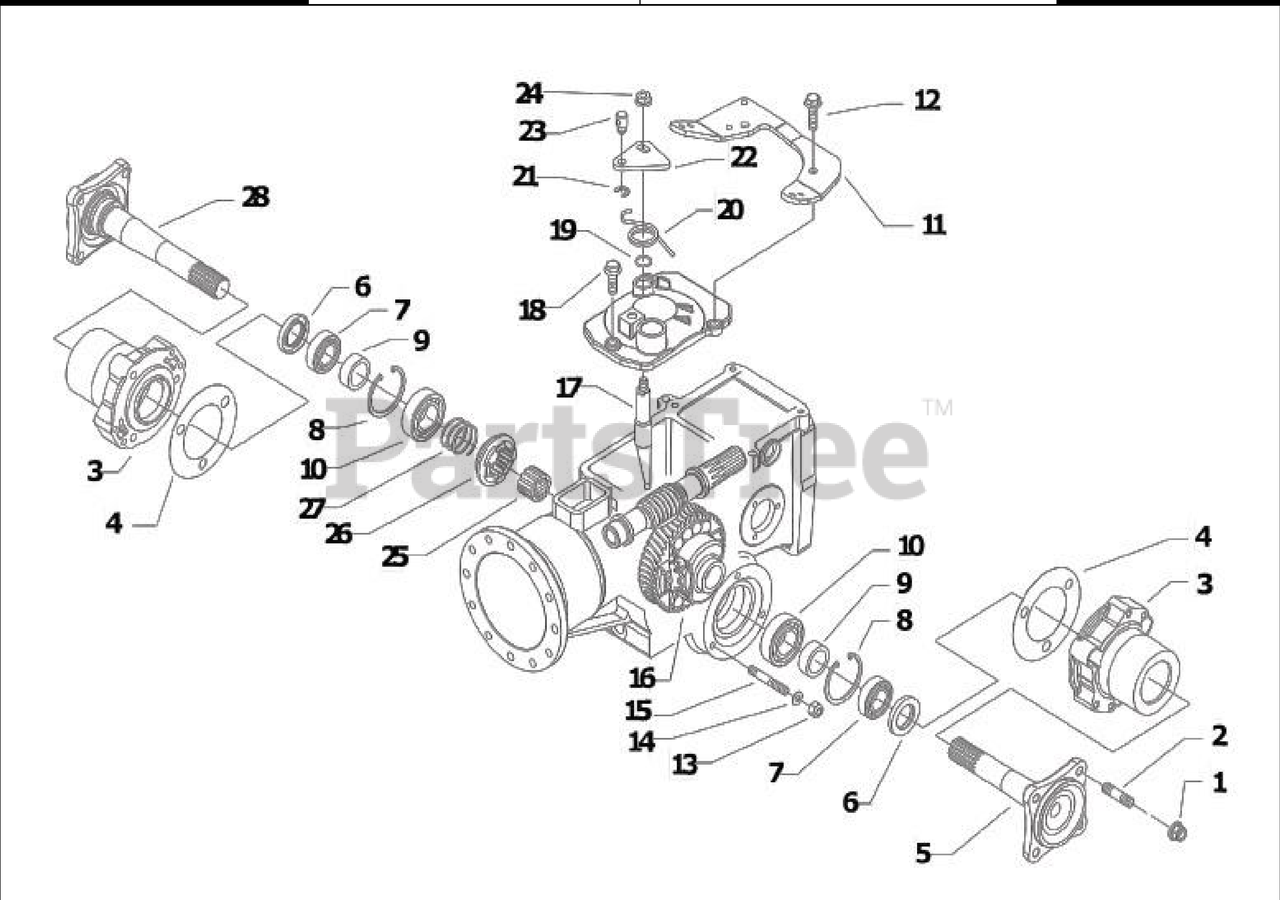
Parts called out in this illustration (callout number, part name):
1	SELFLOCK NUT M10
2	STUD BOLT M10X40X24X12
5	AXLE SHAFT (SHORT)
6	OIL SEAL 30X40X7
7	BEARING 6005 (25X47X12)
8	SNAP RING I 47 DIN 472
11	BRACKET
12	SCREW TE C/F M8X30 DIN 6921 8G
13	HEXAGON SELFLOCK NUT M8
14	SPRING WASHER 8.4
15	STUD BOLT M8X46X20X12
16	DIFFERENTIAL GEAR
18	SCREW TE C/F M8X25 DIN 6921 8G
19	O-RING (14.00X1.78)
21	SNAP RING E 6 UNI 7434
22	LEVER
23	STOP
24	SELFLOCK NUT M8 6S
28	AXLE SHAFT (LONG)
